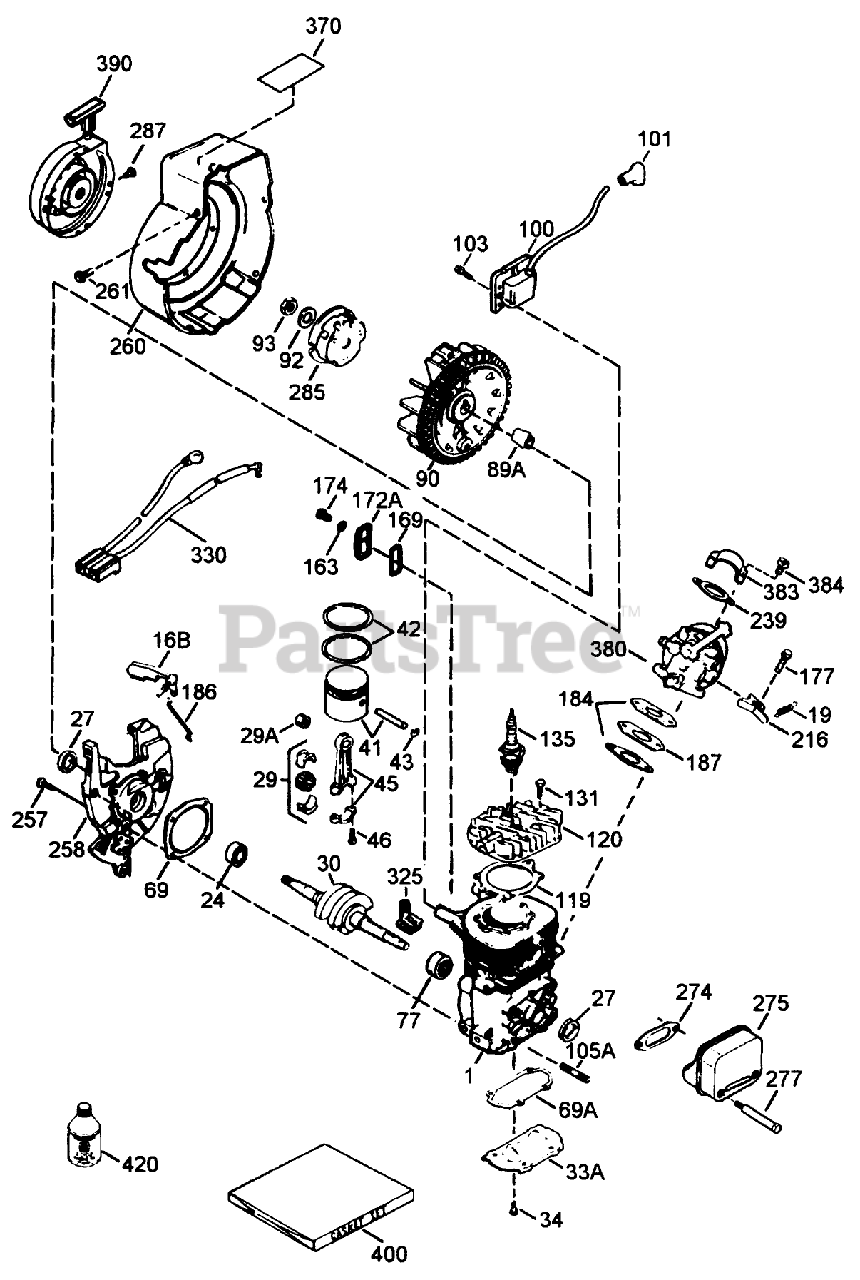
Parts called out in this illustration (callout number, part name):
1	Block Ass-y-Cylinder (Order short block if replacement is required)
16B	Vane-Air
19	Spring-Extention
24	Bearing-Ball
27	Seal-Oil
29	Needle Bearing and Liner Set (37 Needles)
29A	Bearing-Cartridge
30	Crankshaft
33A	Plate-Cover
34	Screw (T-25, 10-24 x 1/2)
41	Piston (Incl. Ref. #43)
42	Ring Set
43	Ring-Retaning
45	Rod Assy.-Connecting (Incl. Ref. #3, 3A 3B)
46	Bolt-Rod, Connecting
69	Gasket-Cover, Cylinder
69A	Gasket-Plate, Cover
77	Bearing-Cartridge
89A	Blade (20 inch)
90	CARB BODY S
92	Washer-Belleville
93	Nut-Flywheel
100	Solid State
101	Cover-Spark Plug
103	Screw
105A	Stud-Cylinder
119	Gasket-Head, Cylinder
120	Head-Cylinder
131	Screw (T-30, 1/4-20 x 3/4)
135	Spark Plug-Resistor (R C J 8Y)
163	Washer
169	Cover-Compression, Release
172A	Cover-Release, Compression
174	Screw (T-25, 10-24 x 1/2)
177	Screw (5/32 Allen, 1/4-20 x 1)
184	Gasket-Carburetor
186	Governor-Link
187	Spacer
216	Lever-Adjusting, Rpm
239	2060A77 WIZARD ROTA
257	Screw (T-30, 1/4-20 x 5/8)
258	Base Ass-y-Blower Housing (Incl Ref. #20)
260	Housing-Blower
261	Screw (1/4-20 x 1/2)
274	Gasket-Exhaust
275	Muffler (Incl. Ref. #274 277)
277	Screw (1/4-20 x 2-3/4)
285	Cup-Starter
287	Screw (8-32 x 21/64)
325	Clip-Wire
330	Harness-Wire
370	Decal-Warning
380	Carburetor (Incl. Ref. #184A)
383	Baffle-Carburetor
384	Screw
390	Rewind Starter
400	Gasket Set
422	2-Cycle Oil (8oz)
